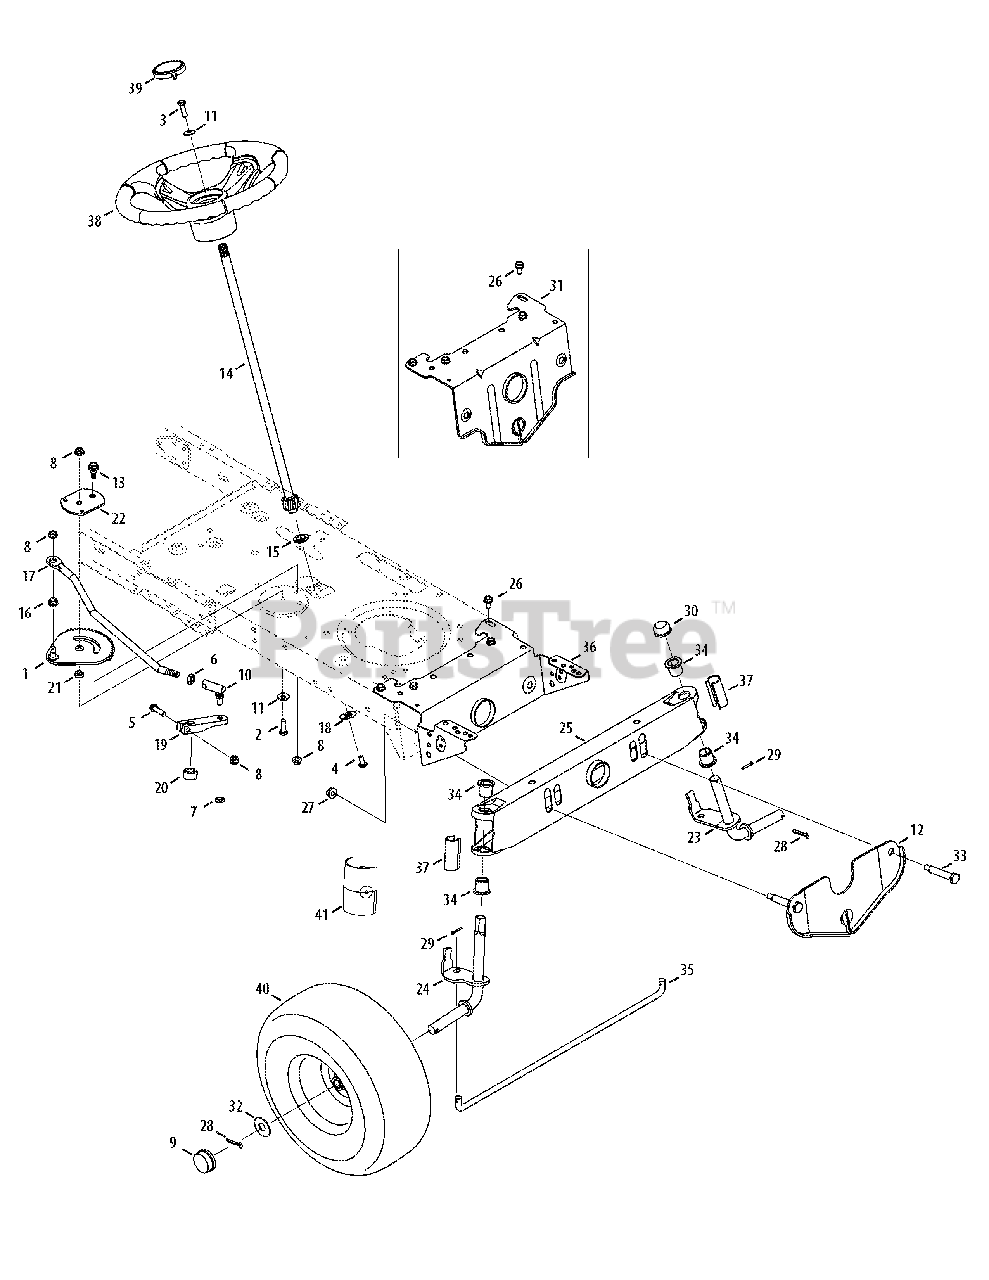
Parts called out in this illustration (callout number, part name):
1	Steering Gear Assembly
2	Hex Scr 5/16 x 1,00 Gr. 5
3	Hex Screw 5/16-18 x 1.00 Special
4	Machine Screw 5/16-18 x .75
5	Hex Screw 5/16-18 x 1.75" Lg.
6	Hex Jam Nut 7/16-20
7	Hex Cent-L Jam Nut 3/8-24
8	Flange Locknut 5/16-18 Gr. F, Nylon
9	Plastic Hub Cap
10	Ball Joint, 7/16 - 20
11	Cupped Washer .345 ID x .88 OD x .060
13	Shoulder Screw .435 x .3485, 5/16-18
14	Steering Shaft, 5/8 Spline x 21.86
15	Hex Flange Bearing 5/8
16	Plastic Bushing .380 ID
17	Steering Drag Link
18	Cap, 1.25 x .16
20	Spacer .710 ID x .125 OD x .56
21	Spacer .322 ID x .625 OD x .21
22	Stabilizer Plate, Gear Segment
26	S-Tapp Scr 5/16-18 x .75
27	Flange Lock-Nut 3/8-16 Gr. F, Nylon
28	Cotter Pin 5/32 x 1.25
29	Cotter Pin 1/8" Dia x .75
30	Push Cap, .750
32	Flat Washer .780 ID x 1.56 OD
33	Shoulder Screw .500 x 2.380, 3/8-16
34	Flange Bearing .760 ID x .937 OD
35	Tie Rod
37	Axle End Cap, Standard
38	Steering Wheel, Standard Grip
38	Steering Wheel, Soft Grip
39	Steering Wheel Cap
41	Pivot Bar End Cap
